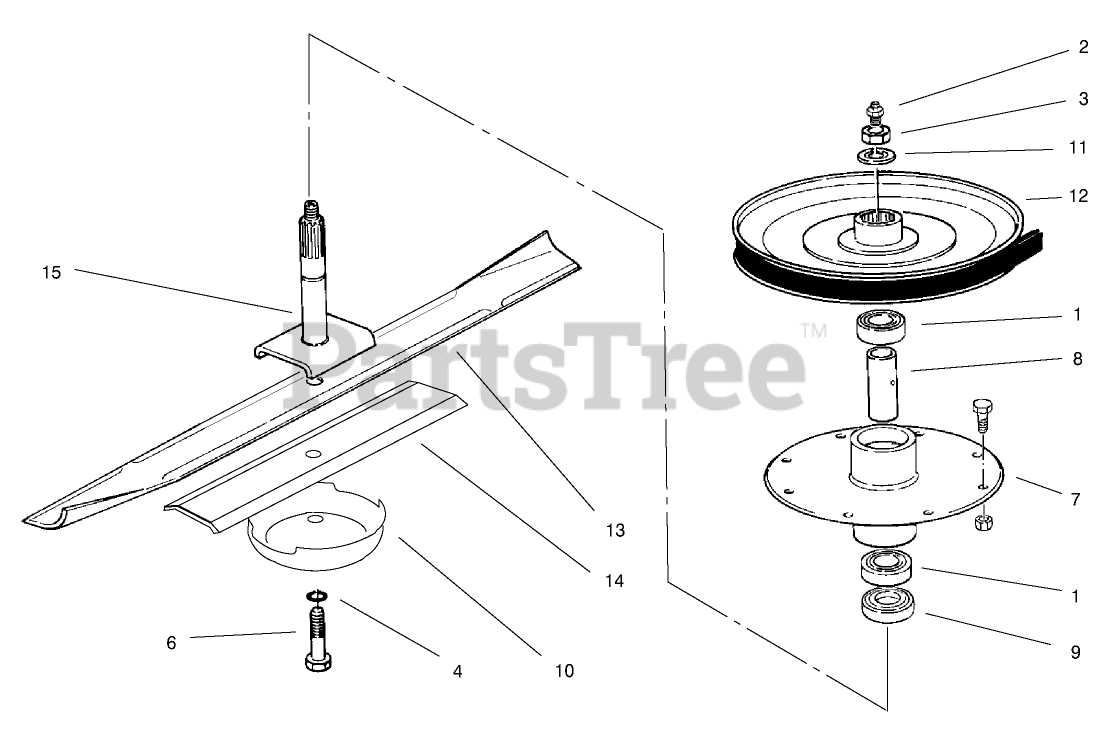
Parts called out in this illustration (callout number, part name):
1	BEARING-BALL
2	FITTING-GREASE
3	NUT-HEX
4	WASHER-LOCK/SP
6	SCREW-BLADE
7	HOUSING-SPINDLE
8	SPACER-BEARING
9	SPACER
10	Cup
11	WASHER
12	PULLEY ASM
13	BLADE-RECYCLER
14	Decal-Danger
15	SHAFT-SPINDLE
